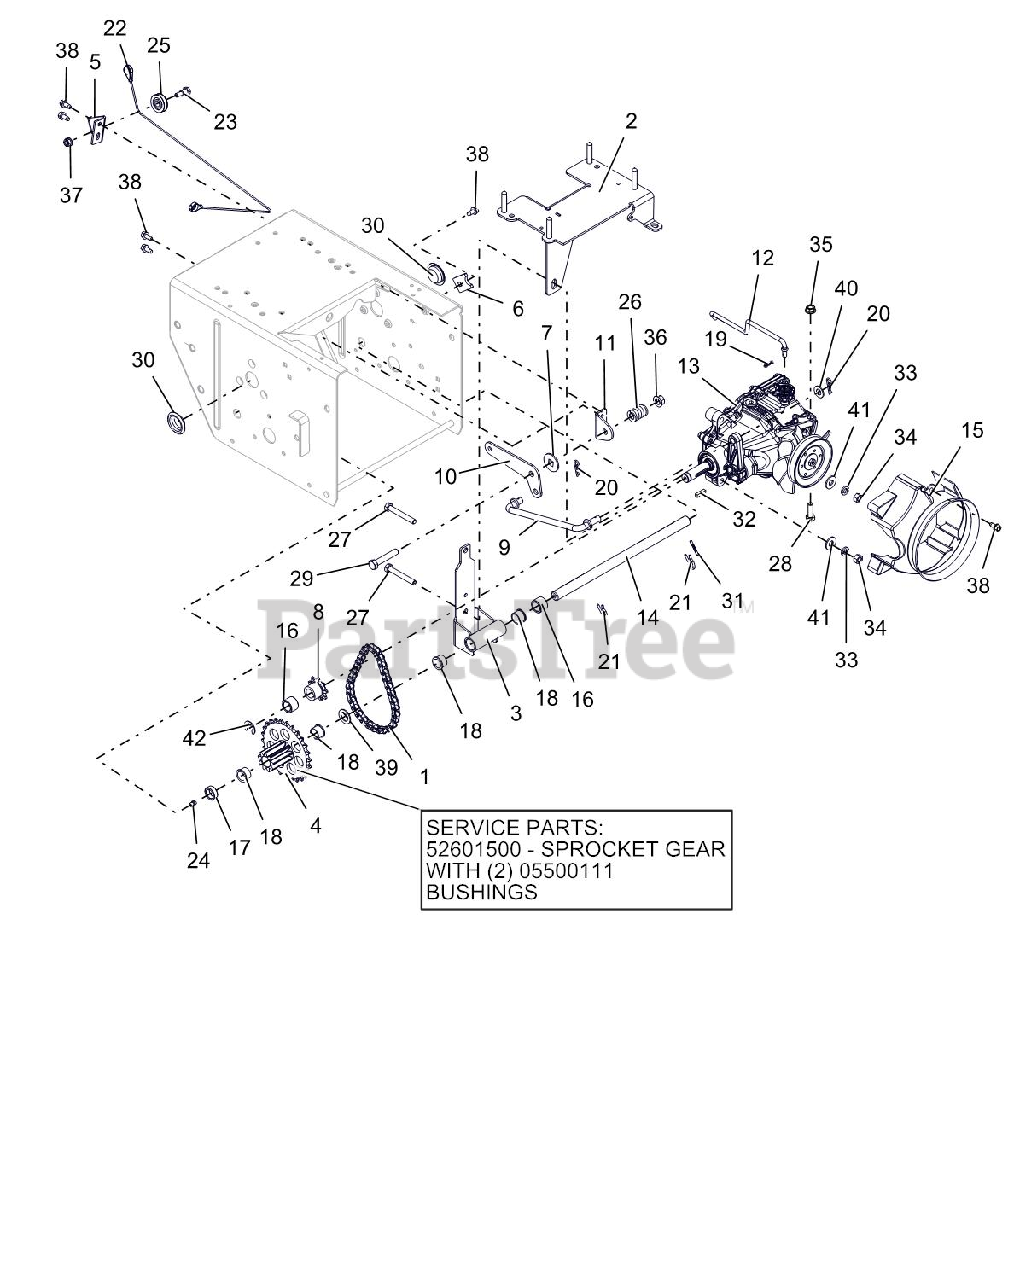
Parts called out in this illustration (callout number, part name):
1	CHAIN - #41, 32 PITCHES
2	BRACKET, HYDROSTATIC TRANS XLG
3	TRANS MOUNT, TENSIONING, WHEEL
4	BSHG-FLG .625X.750X.500X.875
4	PINION & SPROCKET
4	PINION & SPROCKET W/BUSHINGS
5	BRACKET, CABLE PULLEY
6	TAB, ANTI ROTATION
7	FRICTION WASHER
8	SPROCKET, PINION 9T W/KEY
9	ROD, HYDRO TRANS SHIFT
10	PIVOT, HYDRO TRANS SHIFT
11	BRACKET, HYDRO SHIFT PIVOT
12	ROD, HYDRO BYPASS
13	TRANSMISSION, HYDROSTATIC
14	SHAFT, PINION - HARDENED
15	SHROUD, HYDROGEAR RT-310
16	SPACER, .635X.880X.611
17	BSHG-SLV, .635X.880X.305
18	BSHG-FLG .625X.750X.500X.875
19	PIN-HAIR INT .06X.18X.77
20	PIN-HAIR INT .08X.18X1.18 YWZC
21	PIN, SPRING CLIP
22	CABLE, TRACTION, HYDRO PRO
23	BOLT, SHLDR-.375X.375X.25-20
24	ZERK,FITTING .25X.125 DRIVE IN
25	PULLEY, CABLE
26	SG-COMP .187X.56X1.62
27	@BLT-HEX .31-18X2.25 GR5 YWZC
28	@BLT-HEX .31-18X1.00 GR5 YWZC
29	@BLT-HEX .38-16X2.00 GR5 YWZC
30	PLUG, HOLE - 1.125"
31	@PIN-GRV .125X1.00 TP E ALLOY
32	KEY-SQ .188X.75X.188
33	WSHR-LK .312X.097 HVY YWZC
34	@NUT-HEX .31-18 YWZC
35	@NUT-LK-TOP-FLG .31-18 YWZC
36	@NUT-LK-TOP-FLG .38-16 YWZC
37	@NUT-LK-TOP-FLG .25-20 YWZC
38	SCR-TAP .25-20X.50 HWH TR YWZ
39	WSHR-FL-STL .630X1.005X.062 YZ
40	@WSHR-FL-STL.406X.812X.065 YWZ
41	@WSHR-FL-STL.38X.875X.083 YWZC
42	RG-RTNG-EXT .625X.042
